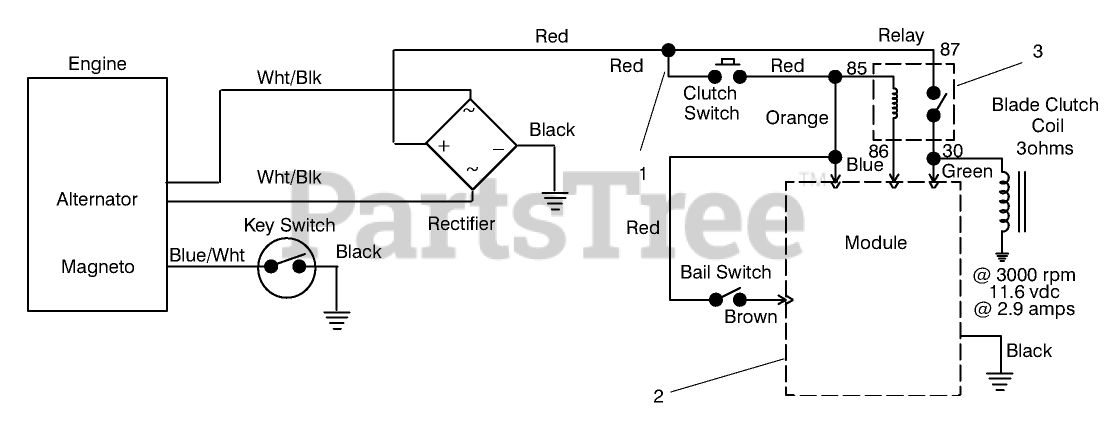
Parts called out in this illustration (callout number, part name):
1	Wire Harness
2	Module
3	RELAY
